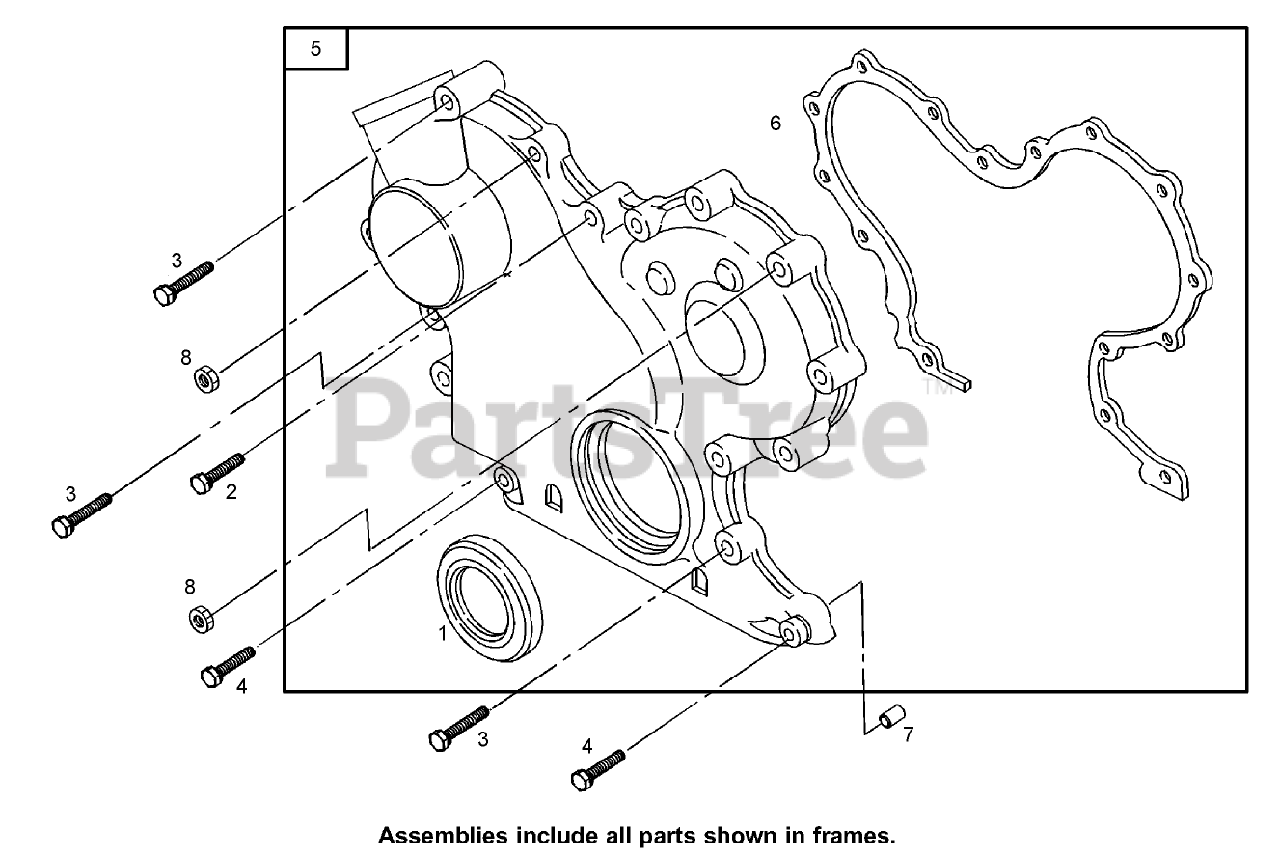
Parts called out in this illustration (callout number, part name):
1	OBS SEAL-OIL
2	SCREW-HEX
3	SCREW-HEX
4	SCREW-HEX
5	GEAR COVER ASM
6	GASKET-COVER, GEAR
7	PIN-LOCATING
8	NUT-HEX, METRIC
